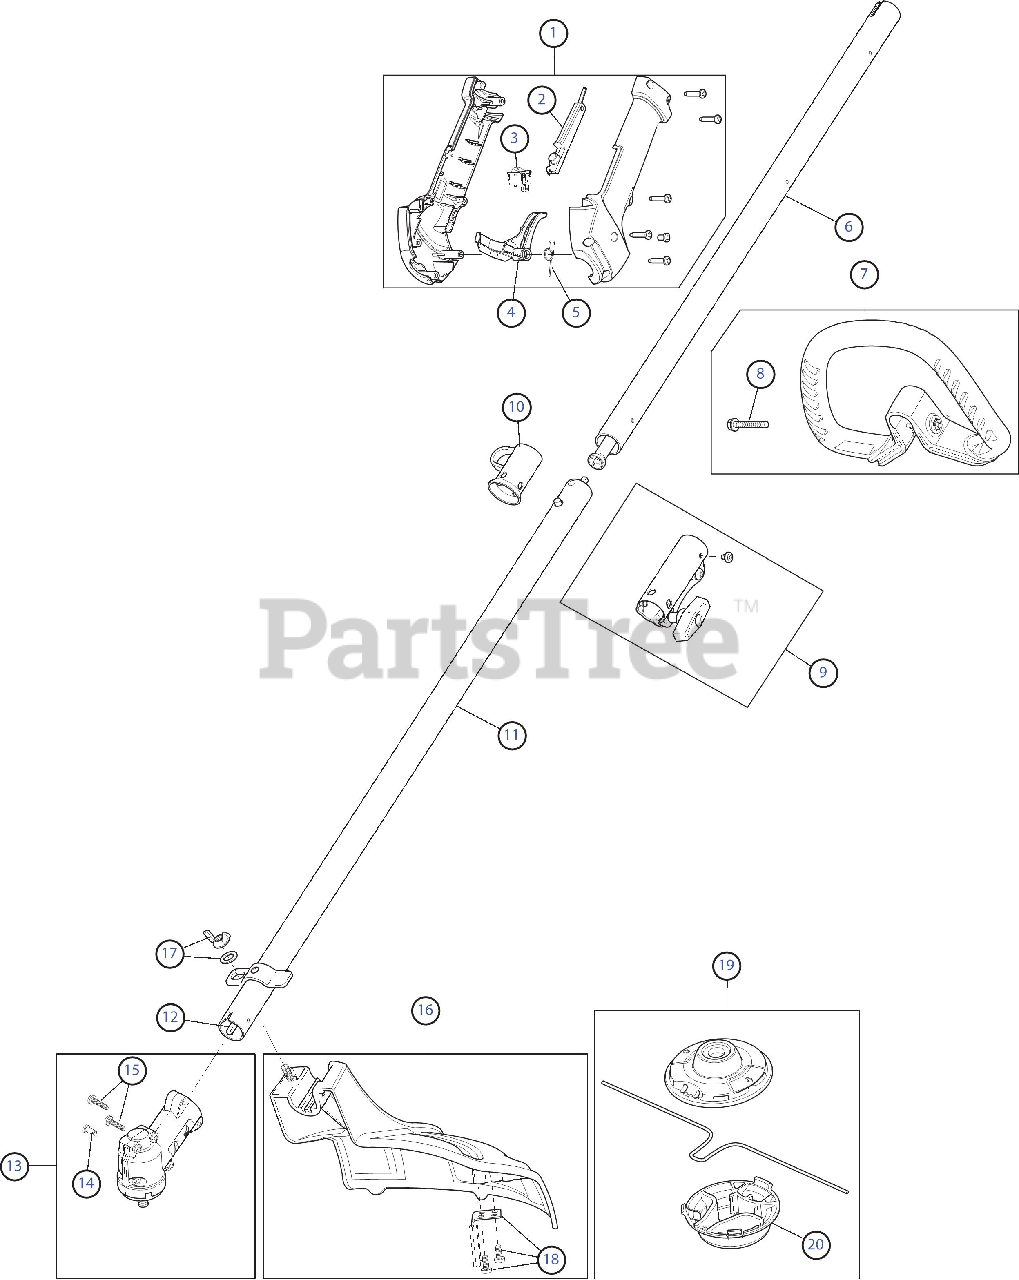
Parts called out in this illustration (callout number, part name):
1	Throttle Housing Assembly (Incl. 2 - 5)
2	Throttle Tigger Lock-Out
3	Throttle Switch Assembly
4	Throttle Trigger
5	Throttle Trigger Spring
6	Upper Shaft Housing Assembly
7	D-Handle (Incl. 8)
8	D-Handle Bolt
9	Split Boom Coupler
10	Hanger
11	Lower Shaft Housing Assembly
12	Lower Flexible Drive Shaft
13	Gearbox Assembly (Incl. 14 & 15)
14	Gearbox Anti-Rotation Screw
15	Gearbox Mounting Hardware
16	Shield Assembly (Incl. 17 & 18)
17	Shield Mounting Hardware
18	Blade Assembly
19	Cutting Head Assembly (Incl. 20)
20	Glide Cap
